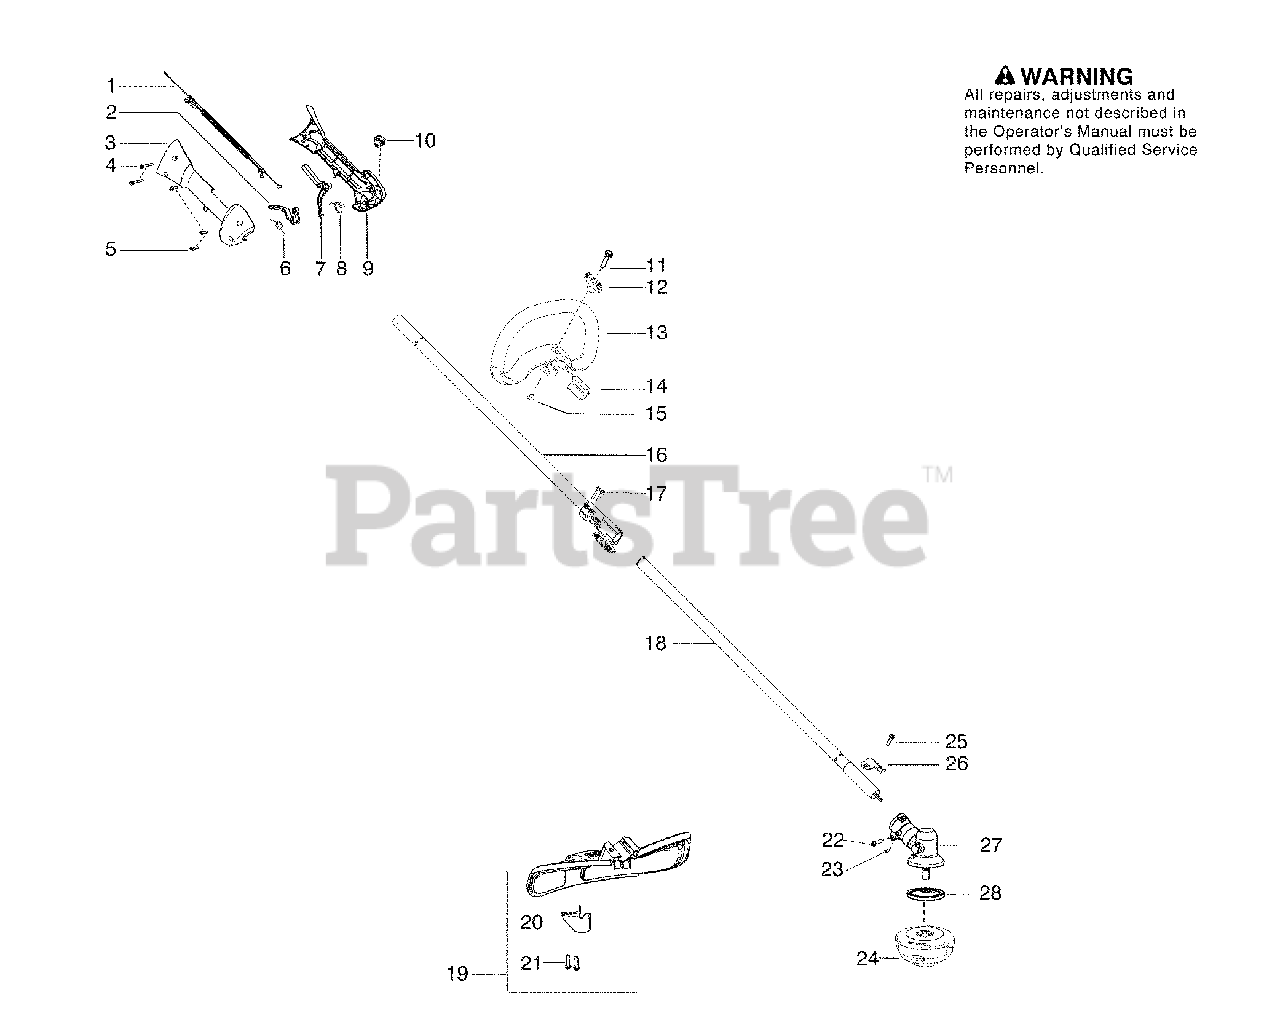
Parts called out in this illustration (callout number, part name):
1	Assy-Cable/Wire Harness
3	Housing-Throttle (RH)
6	Spring-Trigger
7	Lockout-Throttle
8	Spring-Lockout
9	Housing-Throttle (LH)
10	Kit-Switch
11	Screw
12	Knob
13	Assy - Loop Handle
14	Spacer
16	Kit-Driveshaft Upper
18	Kit-Lower Shaft
19	Kit-Shield
20	Limiter-Line
24	Assy-T25 Cutting Head
26	Bracket-Shield
27	Assy-Gearbox
28	Driver Disc
